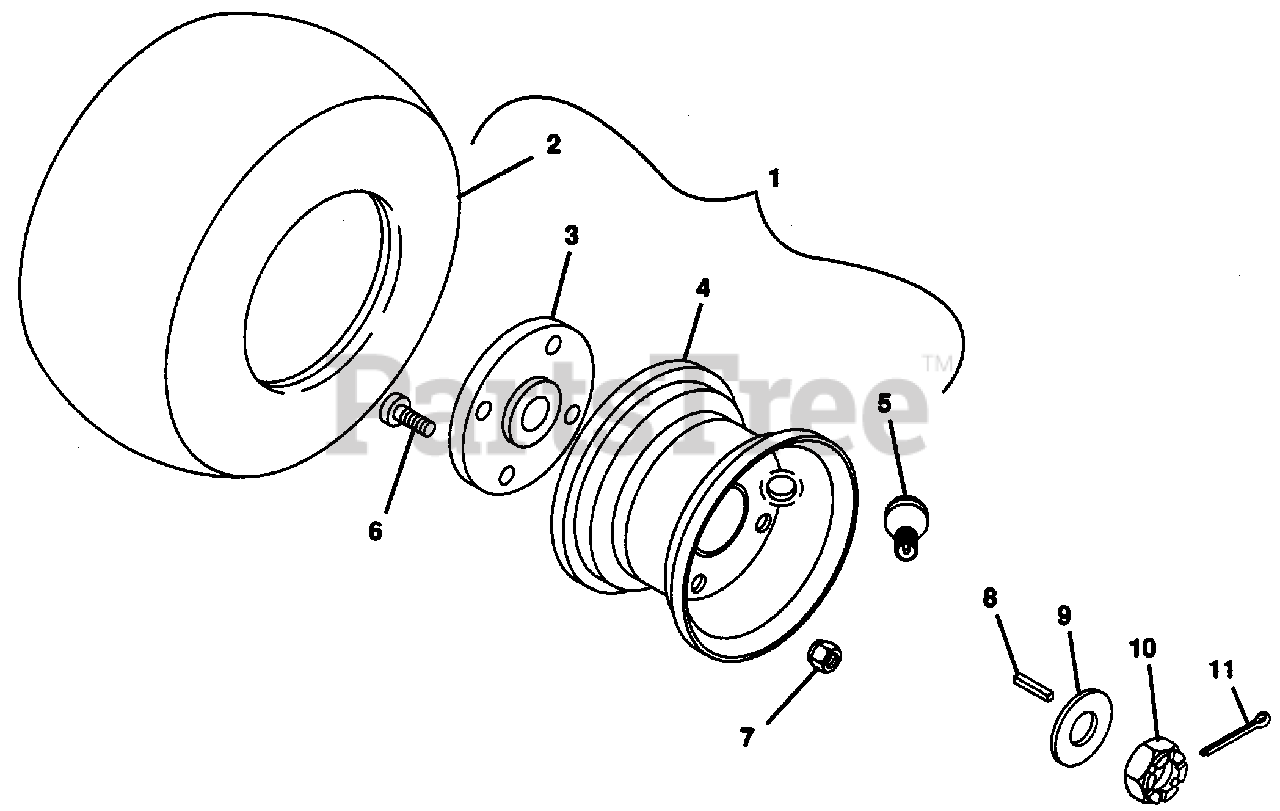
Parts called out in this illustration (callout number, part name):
1	Wheel Asm., 16x6.50-8
2	Tire, 16x6.50-8
3	Assembly, Hub
4	Assembly, Rim
5	Assembly, Valve Stem
6	Bolt, 1/2-20x1.25 Pan Head
7	Nut, Rim
8	Key, Square .187x.750
9	Washer, Flat .813x1.37x.100
10	Nut, Hex 3/4-28 Slotted
11	Pin, Cotter .062x1.00
